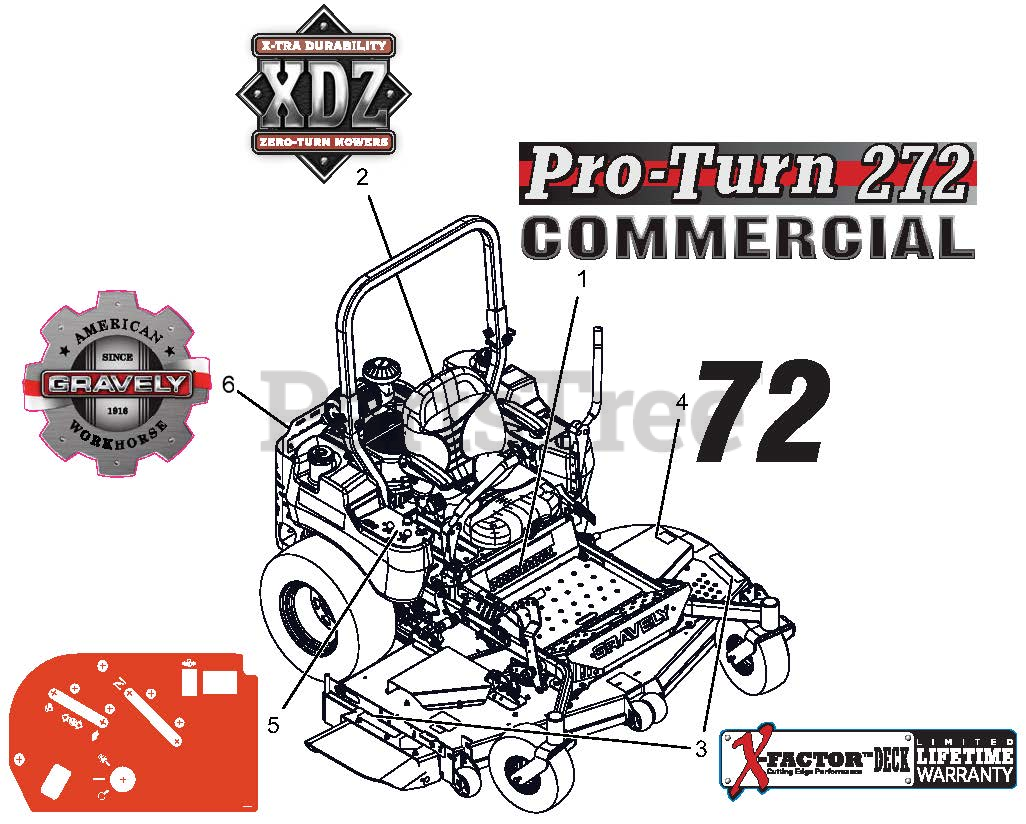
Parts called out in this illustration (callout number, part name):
1	DECAL, PRO-TURN 272
2	DECAL, XDZ
3	DECAL, X-FACTOR DECK
4	DECAL, 72"
5	DECAL, CONTROL PANEL NON-EFI
6	DECAL, GRAVELY HERITAGE-LARGE
